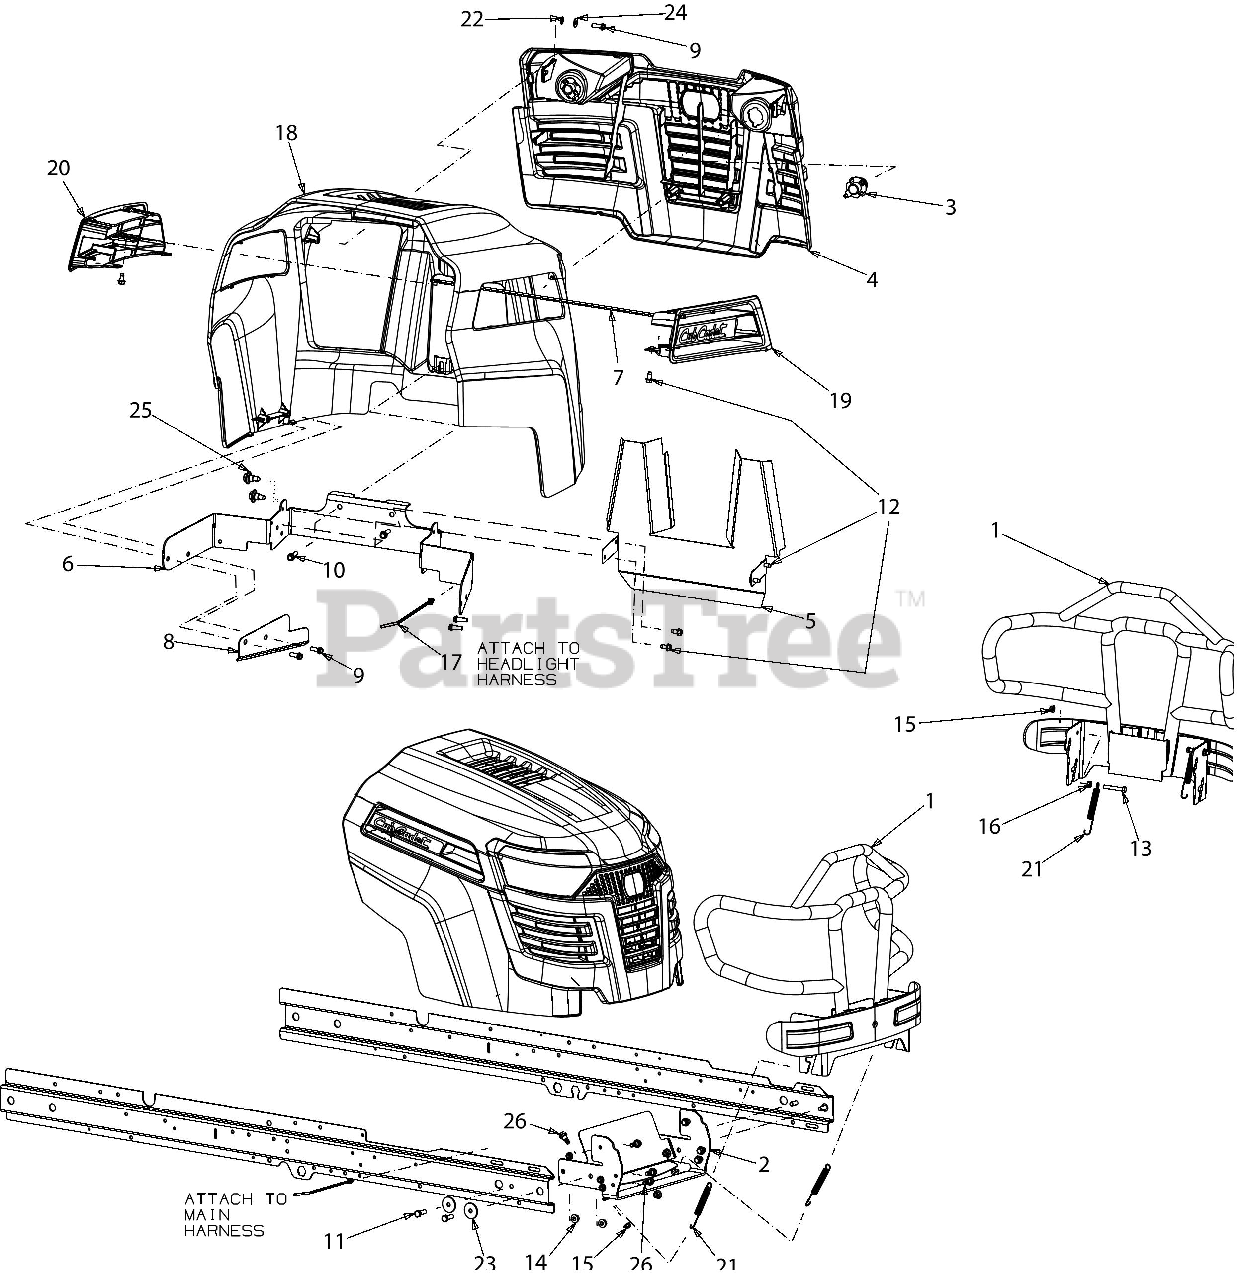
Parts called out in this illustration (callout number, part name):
1	BRUSH GUARD ASSEMBLY
2	DEBRIS GUARD ASSEMBLY
3	MINIATUURE BULB 12V
3	HEADLIGHT SOCKET
4	GRILLE ASSEMBLY
5	DEFLECTOR SHIELD
6	HOOD PIVOT BRACKET
7	HOOD CROSS BRACE
8	HEAT EXHAUST SHIELD
9	SCREW 1/4 x .750
10	SCREW 5/16-14 x 1
11	SCREW 3/8-16 x 1 GR5
12	SCREW 1/4-20 X.500
13	SCREW 5/16-18 x 2.0 GR5
15	HEX FLANGE NUT
16	HEX NUT
17	PUSH MOUNT TIE
18	HOOD (CUB YELLOW)
19	HOOD SCOOP (RH)
20	HOOD SCOOP (LH)
21	EXTENSION SPRING .54ODX5.0LG
22	LOCK WASHER 1/4
23	FLAT WASHER .390x1.500x.134
24	FLAT WASHER .271:.630:.065
25	SHOULDER SCREW .43X.29X5/16-18 TT
26	SHOULDER SCREW .43 X.35,5/16-18
